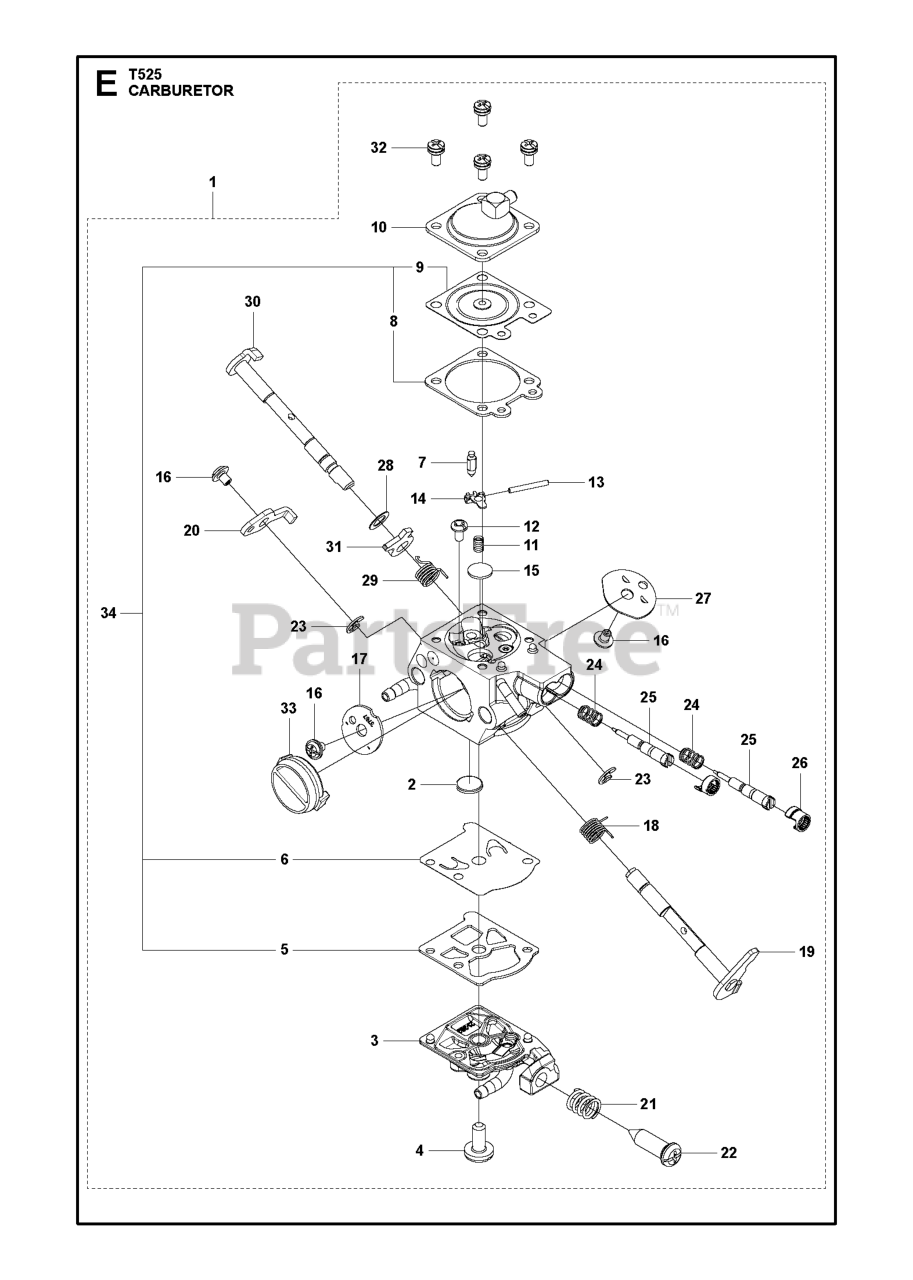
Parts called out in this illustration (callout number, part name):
1	CARBURETTOR
2	SCREEN
3	COVER ASSY PUMP
6	DIAPHRAGM, FUEL PUMP
7	VALVE INLET
11	SPRING 848L9581C0
17	VALVE THROTTLE
19	SHAFT ASSY THROTTLE
20	LEVER THROTTLE
22	SCREW, IDLE
25	NEEDLE HIGH SPEED
26	CAP LIMITER
27	VALVE T207581450
30	SHAFT ASSY CHOKE
32	SCREW ASSY
33	RING MANIFOLD
34	GASKET KIT
